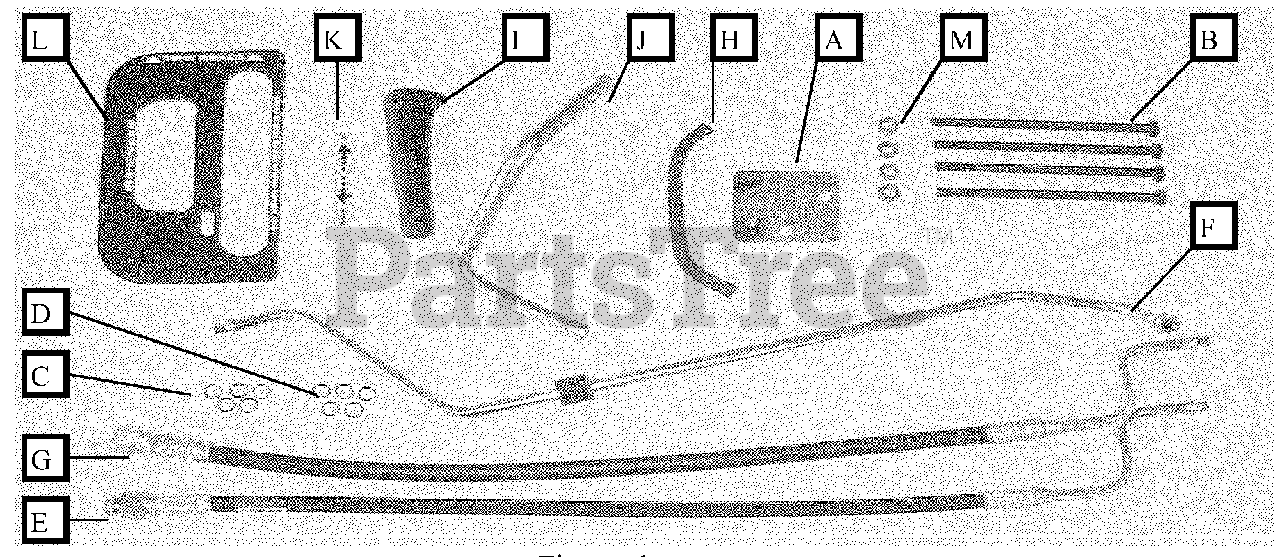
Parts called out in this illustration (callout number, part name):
A	Template Bracket
B	Hex Cap Screw 1/4-20 X 7.75 GR5
C	Back-up O-Ring
D	O-Ring .301 ID X .070 Dia.
E	Hydraulic Hose 3 point
F	Hydraulic Tube (Aux. from Steering)
G	Hydraulic Hose 3 point
H	Trim Strip
I	Lift Handle Knob
J	Hydraulic Valve Handle #4
K	Fourth Valve Label
L	Template Label
M	Hex Lock Nut 1/4-20
